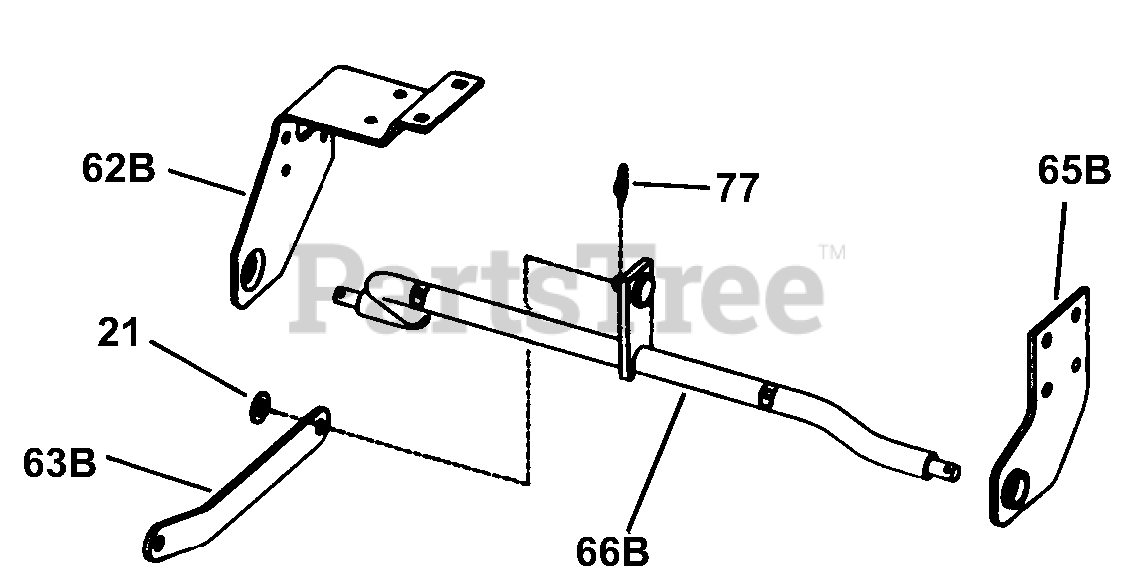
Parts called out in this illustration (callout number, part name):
21	WASHER, 3/8 Bright Zinc, Flat
62B	BRACKET, Rear Lift/PTO Lever
63B	LINK, Lift
65B	BRACKET, Rear Hanger- LH
66B	WELDMENT, Rear Lift
77	COTTER PIN, 1/16 x 1-7/32" Self Lock
